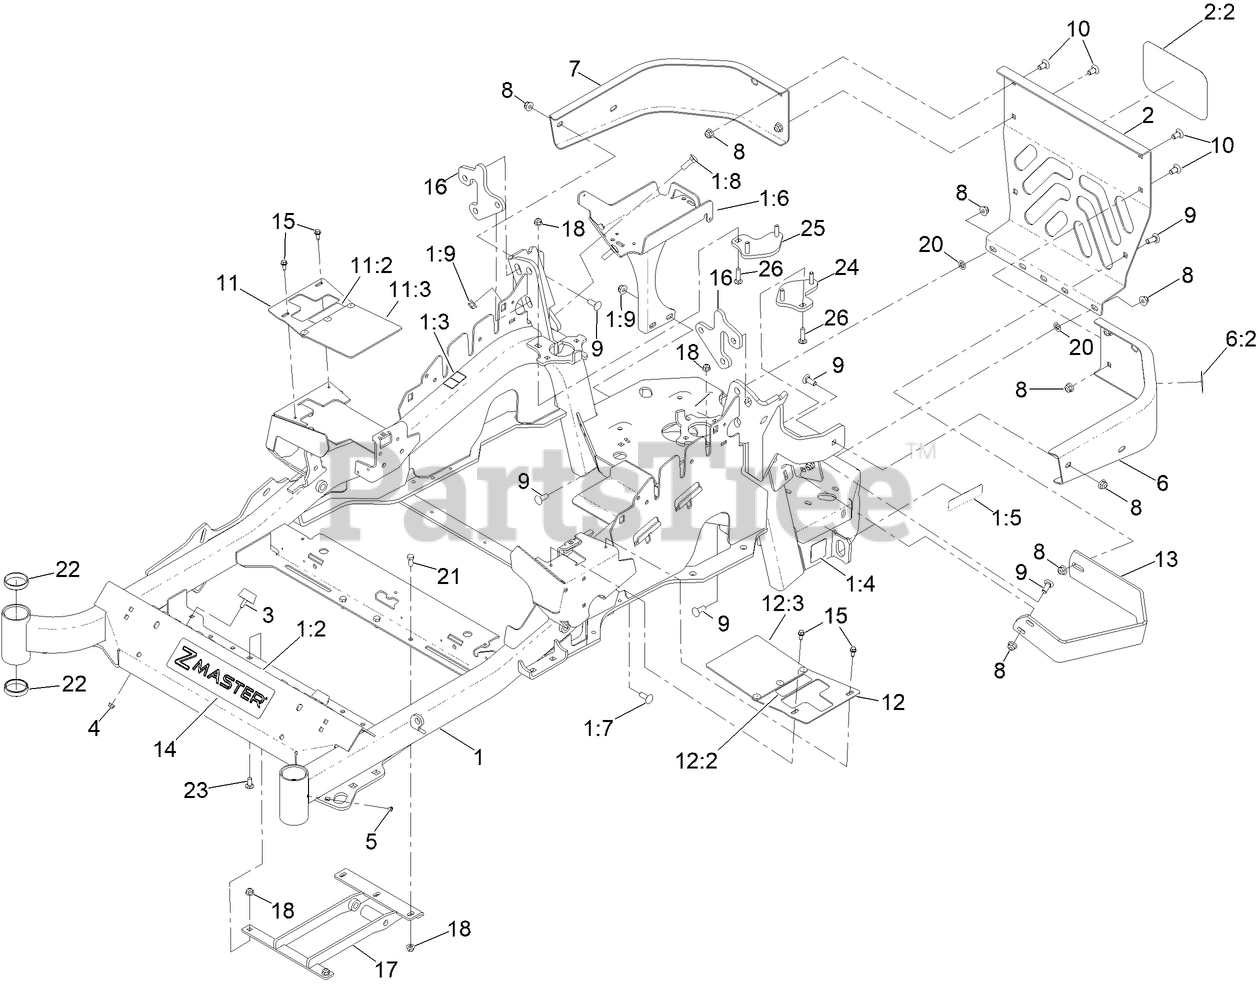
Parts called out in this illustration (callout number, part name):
1	MAINFRAME SERVICE ASM - 48/52
1:2	DECAL-DANGER
1:3	DECAL-WARNING
1:4	DECAL-HAZARD, PINCHED FINGER
1:5	DECAL-ARRESTOR, SPARK
1:6	BATTERY MOUNT ASM
1:7	SCREW-CARR
1:8	BOLT-CARR
1:9	NUT-HF, NI
2	REAR GUARD ASM
2:2	DECAL
3	BUMPER
4	NUT-HF
6	LH BUMPER ASM
6:2	DECAL-WARNING
7	BUMPER-RH
8	NUT-HF, NI
9	SCREW-CARR
10	SCREW-CARR
11	RH MOTION CONTROL COVER ASM
11:2	DECAL-CONTROL, MOTION
11:3	FLAP-RUBBER
12	LH MOTION CONTROL COVER ASM
12:2	DECAL-CONTROL, MOTION
12:3	FLAP-RUBBER
13	GUARD-MUFFLER
14	DECAL-CONSOLE
15	SCREW-HWH
16	PLATE-MOUNT, SHOCK
17	MOUNT-LOWER
18	NUT-HF, NI
20	NUT-PUSH
21	SCREW-HH
22	CUP-BEARING
23	SCREW-CARR
24	LH PLATE ASM (W/STUDS)
25	RH PLATE ASM (W/STUDS)
26	SCREW-CARR
